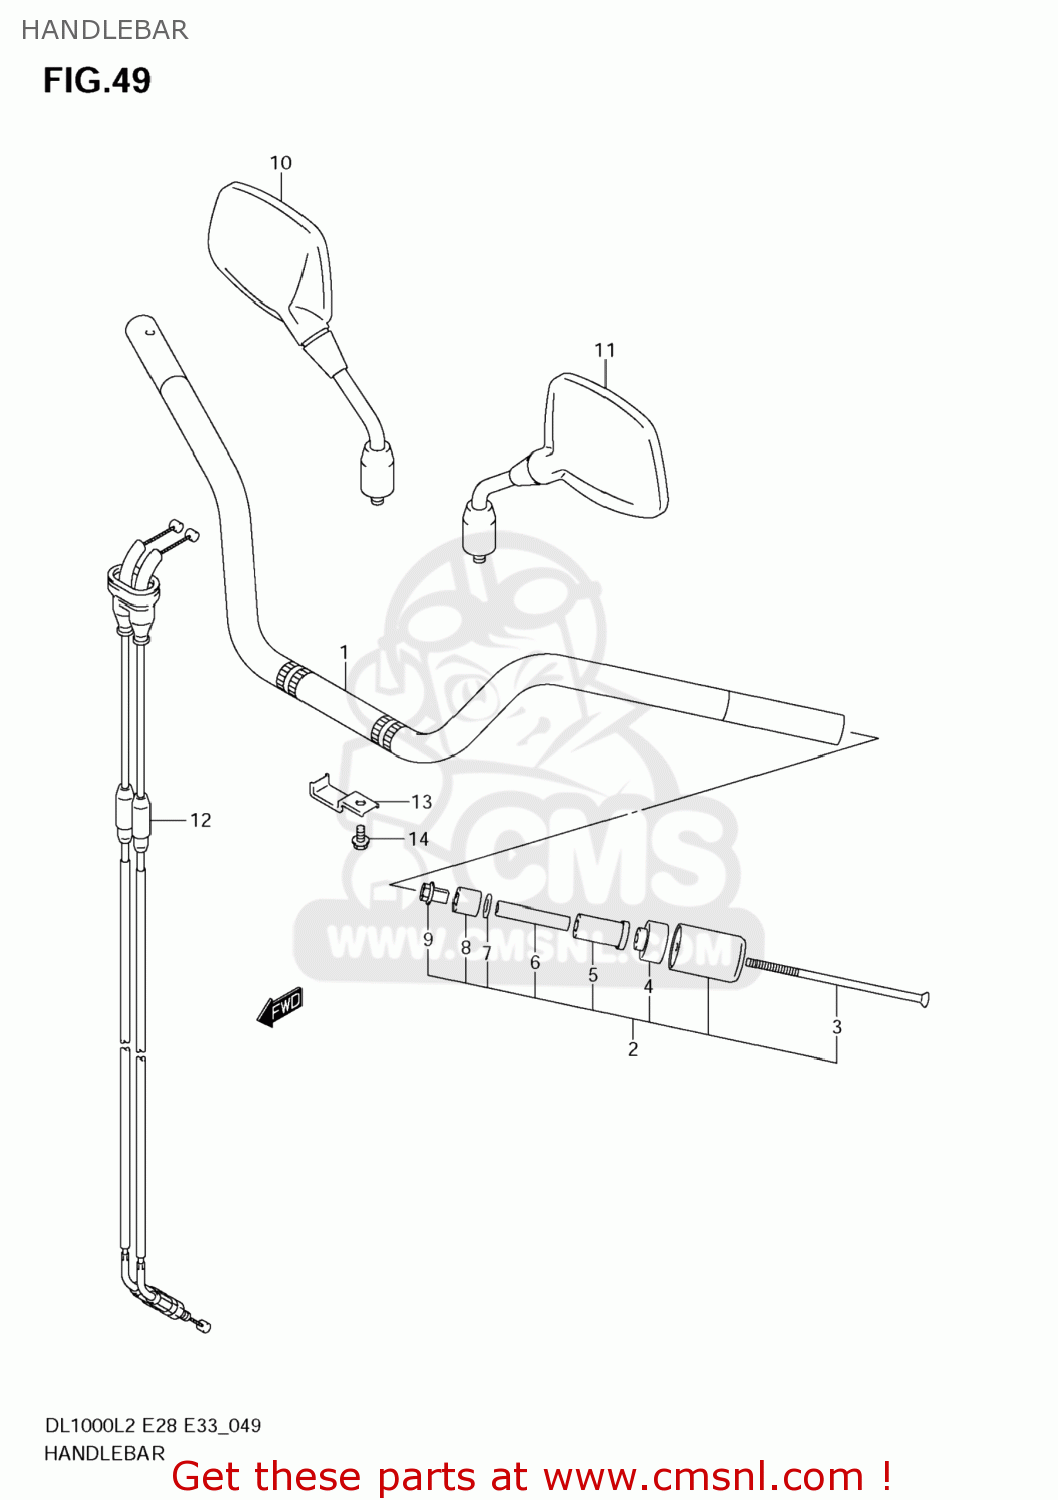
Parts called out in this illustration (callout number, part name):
1	HANDLEBAR
2	BALANCER SET,HANDLEBAR
3	SCREW(6X140)
4	SPACER,KNUCKLE COVER
5	EXPANDER
6	SPACER,EXPANDER
7	WASHER(6.5X16X1.6)
8	EXPANDER,HANDLE BALANCER
9	NUT,HANDLE BALANCER
10	MIRROR ASSY,RR VIEW,R
11	MIRROR ASSY,RR VIEW,LH
12	CABLE ASSY,THROTTLE
13	GUIDE,THROTTLE CABLE
14	SCREW
